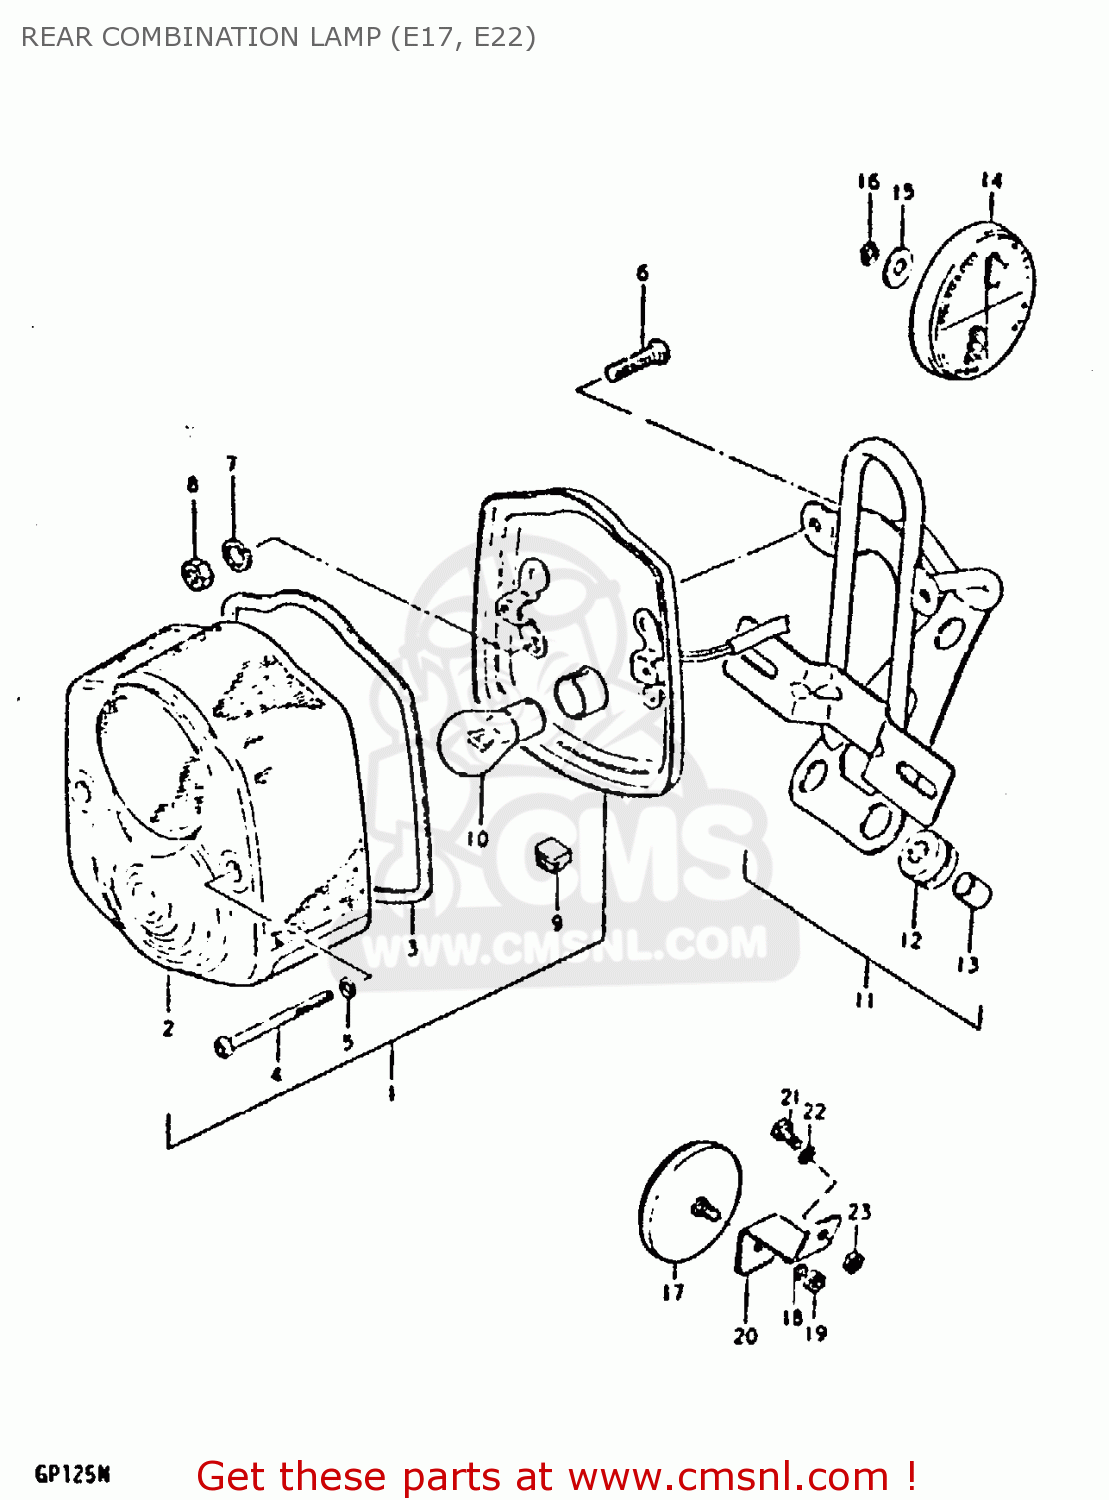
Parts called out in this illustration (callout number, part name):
1	LAMP ASSY, TAIL
2	LENS
3	GASKET (NAS)
4	SCREW
5	GASKET (NAS)
9	GROMMET
10	BULB (6V,21/5W)
14	REFLEX REFLECTOR,FR
17	REFLECTOR,REFLEX
18	LOCK WASHER
19	NUT
20	BRACKET
21	BOLT
22	LOCK WASHER
23	NUT
